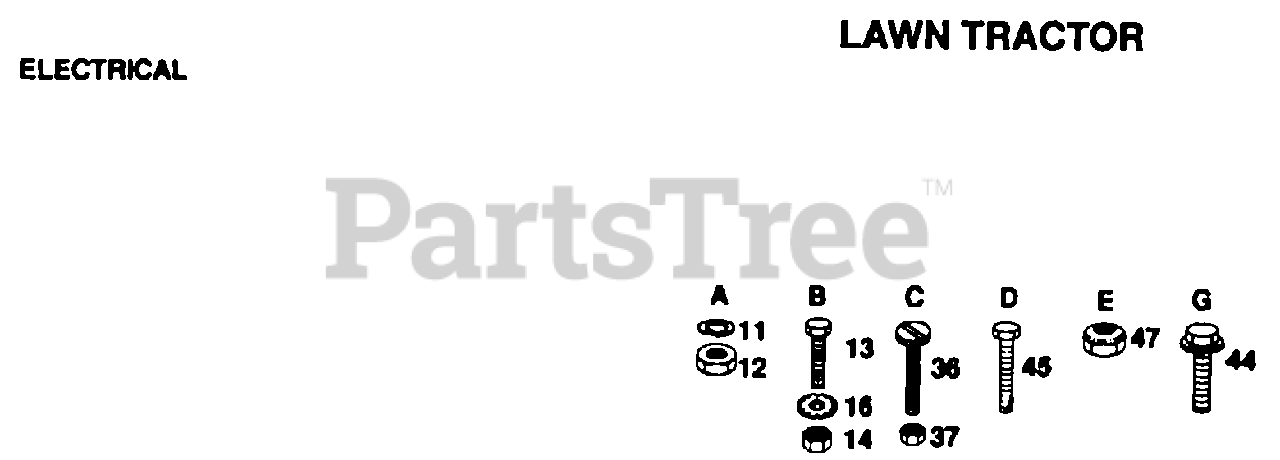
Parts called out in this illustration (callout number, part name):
12	NUT
13	BOLT
14	NUT
37	"NUT,KEPS"
44	SCREW LT
45	SCREW
